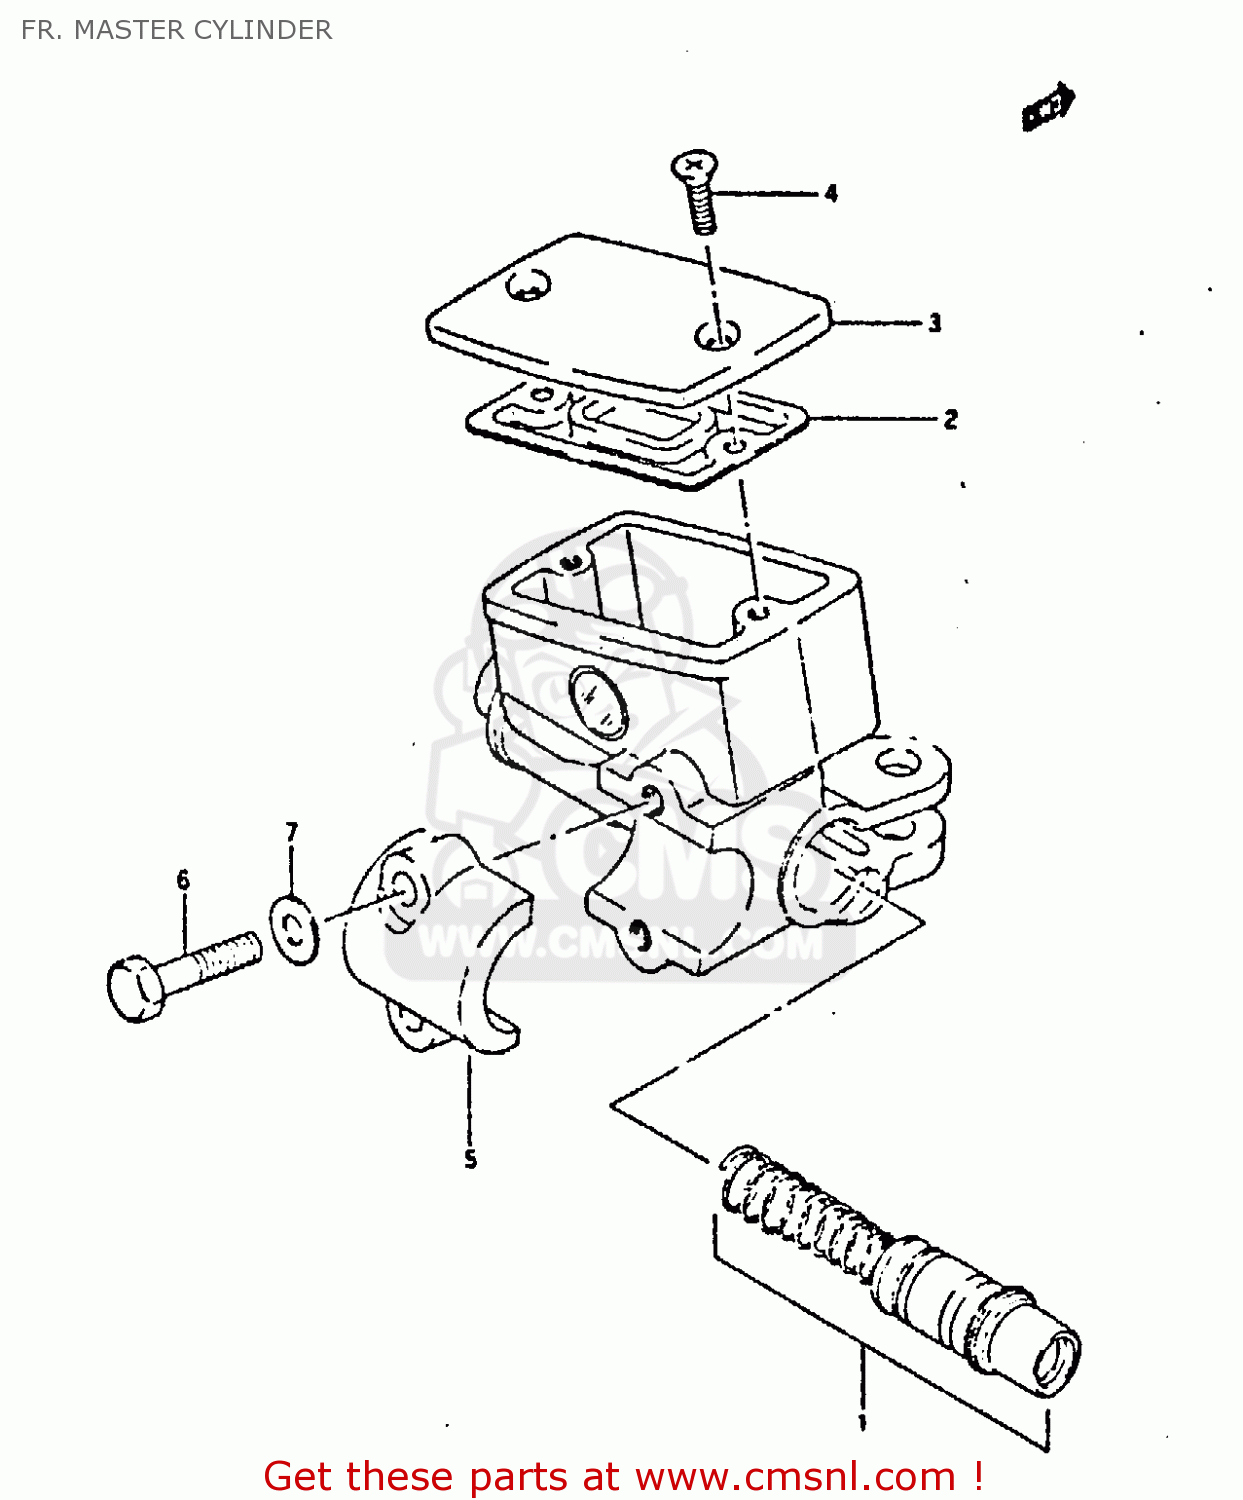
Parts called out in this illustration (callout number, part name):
1	PISTON & CUP SET
3	CAP
5	HOLDER,MASTER CYLINDER
6	BOLT
7	WASHER
